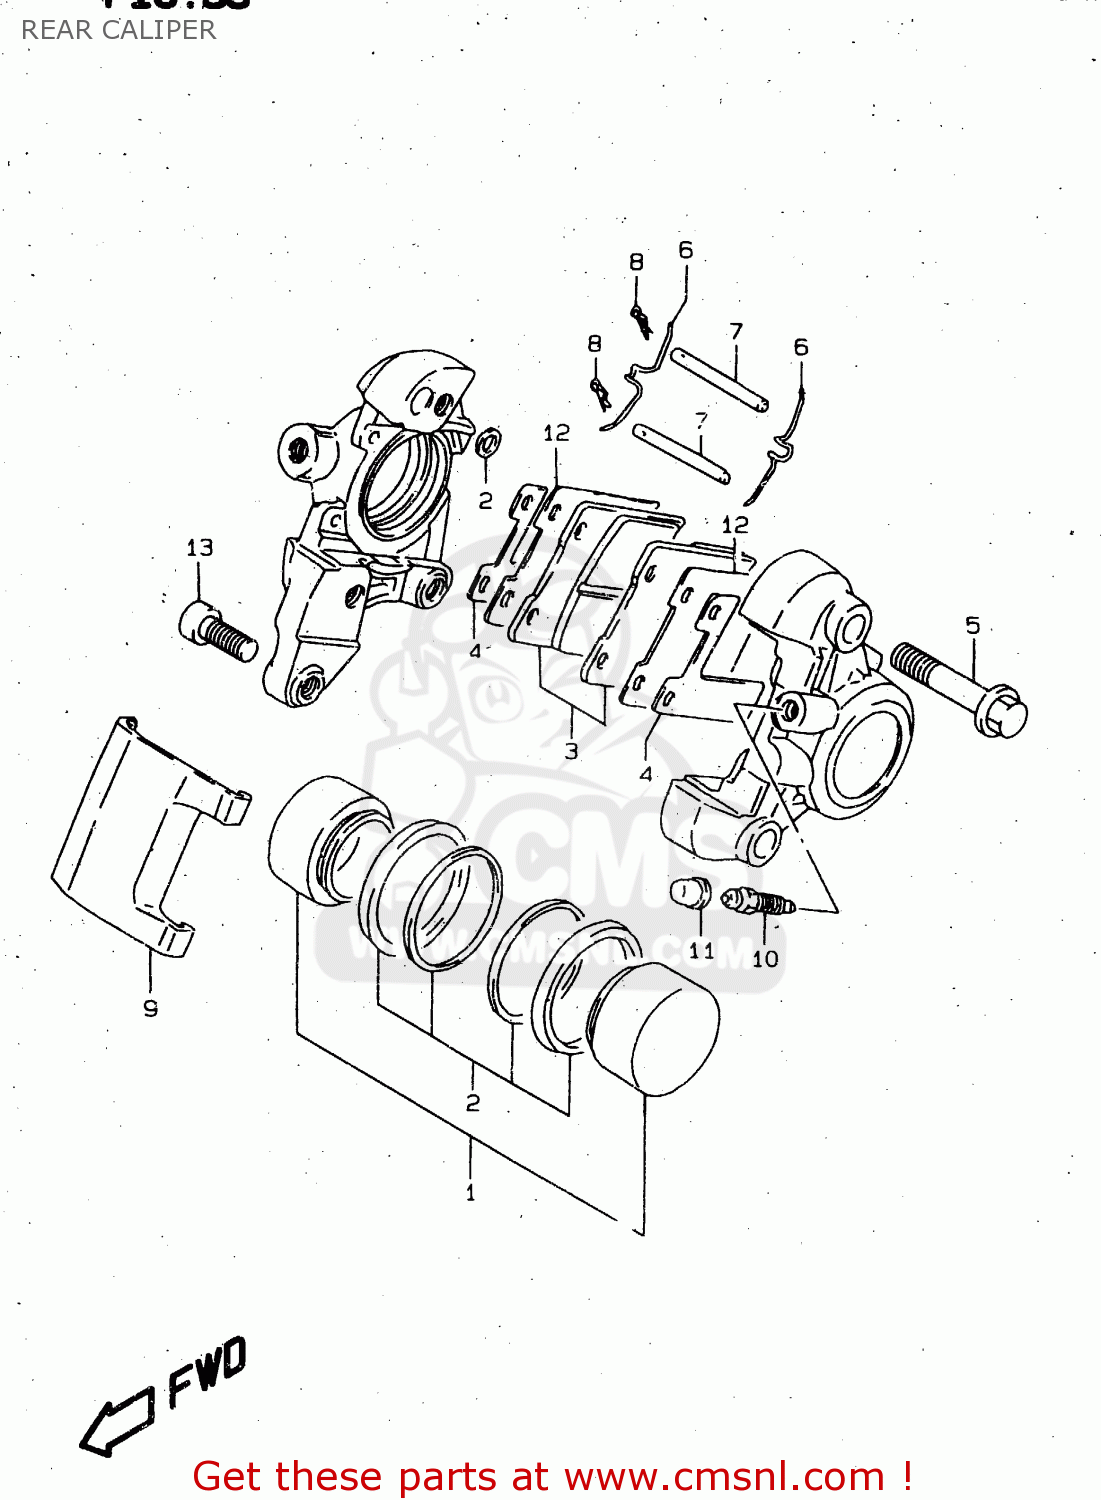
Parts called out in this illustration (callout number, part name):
1	PISTON SET
2	SEAL SET,PISTON
3	PAD SET (NAS)
4	SHIM
5	BOLT,HOUSING
6	SPRING
7	PIN,PAD
8	CLIP,PAD PIN
9	COVER
10	BLEEDER
11	CAP,BLEEDER PLUG
12	SHIM,PAD
13	BOLT
